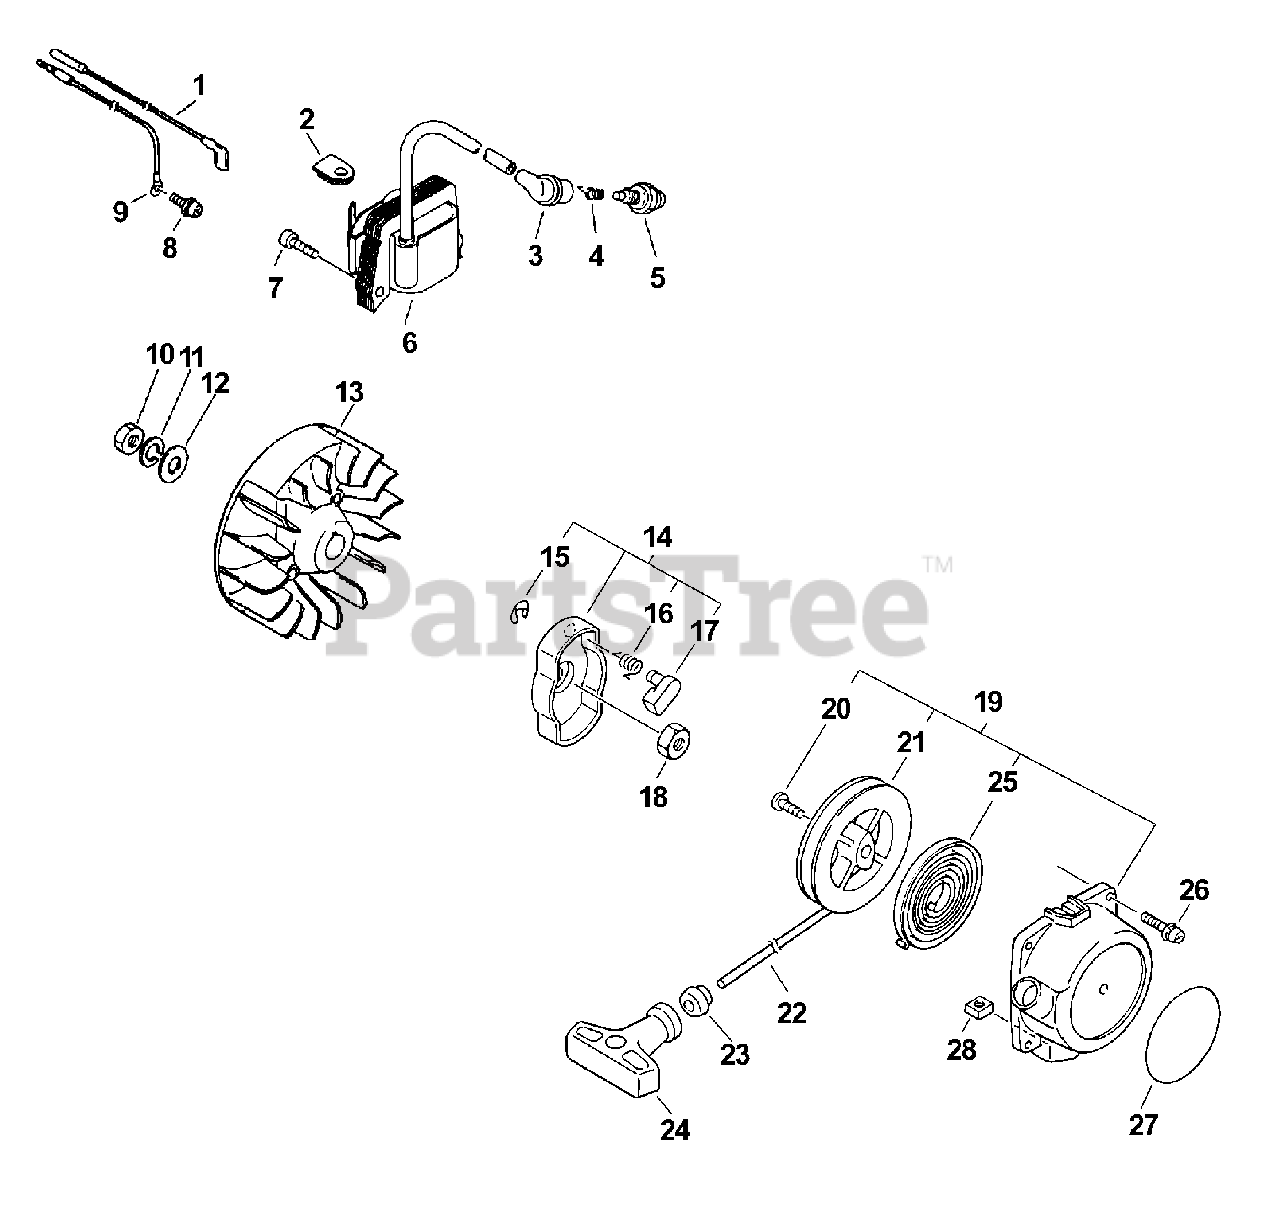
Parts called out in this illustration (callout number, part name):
1	LEAD - IGNITION 145 MM
2	GROMMET
3	CAP, SPARK PLUG
4	TERMINAL, SPARK PLUG
5	SPARK PLUG - BPM-7Y
5	SPARK PLUG - BPMR7A
6	COIL, IGNITION
7	BOLT 5×20
8	SCREW 5×10
9	LEAD - GROUND
10	NUT 8×1.25
11	WASHER, SPRING 8
12	WASHER 8.5×16×1.2
13	FLYWHEEL
14	PAWL ASSY, STARTER
15	E-RING 4
16	SPRING, RETURN
17	PAWL, STARTER
18	NUT 8×1.25
19	STARTER ASSY, RECOIL
20	SCREW
21	REEL, ROPE
22	ROPE, STARTER
23	GUIDE, ROPE
24	GRIP, STARTER
25	SPRING, RECOIL
26	BOLT 4×14
27	LABEL, ECHO
28	NUT M5
